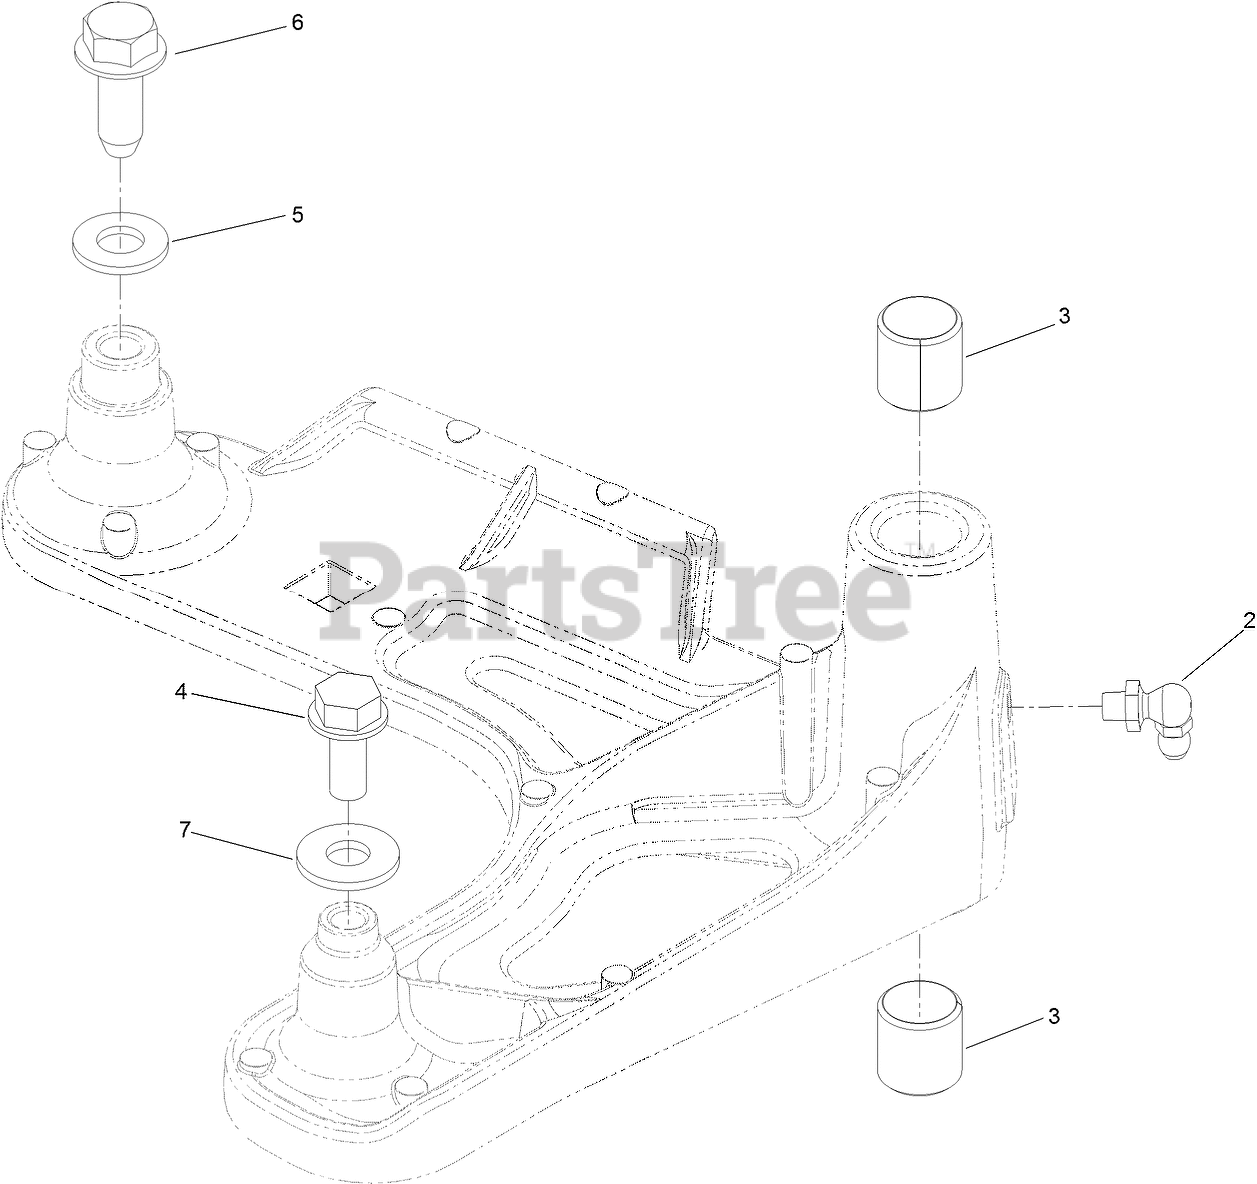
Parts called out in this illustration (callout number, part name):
2	FITTING-GREASE, 90 DEG
3	SLEEVE-BEARING
4	SCREW-THD ROLL, HWH
5	WASHER-FLAT
6	SCREW-FORMING, THREAD
7	WASHER-FLAT
